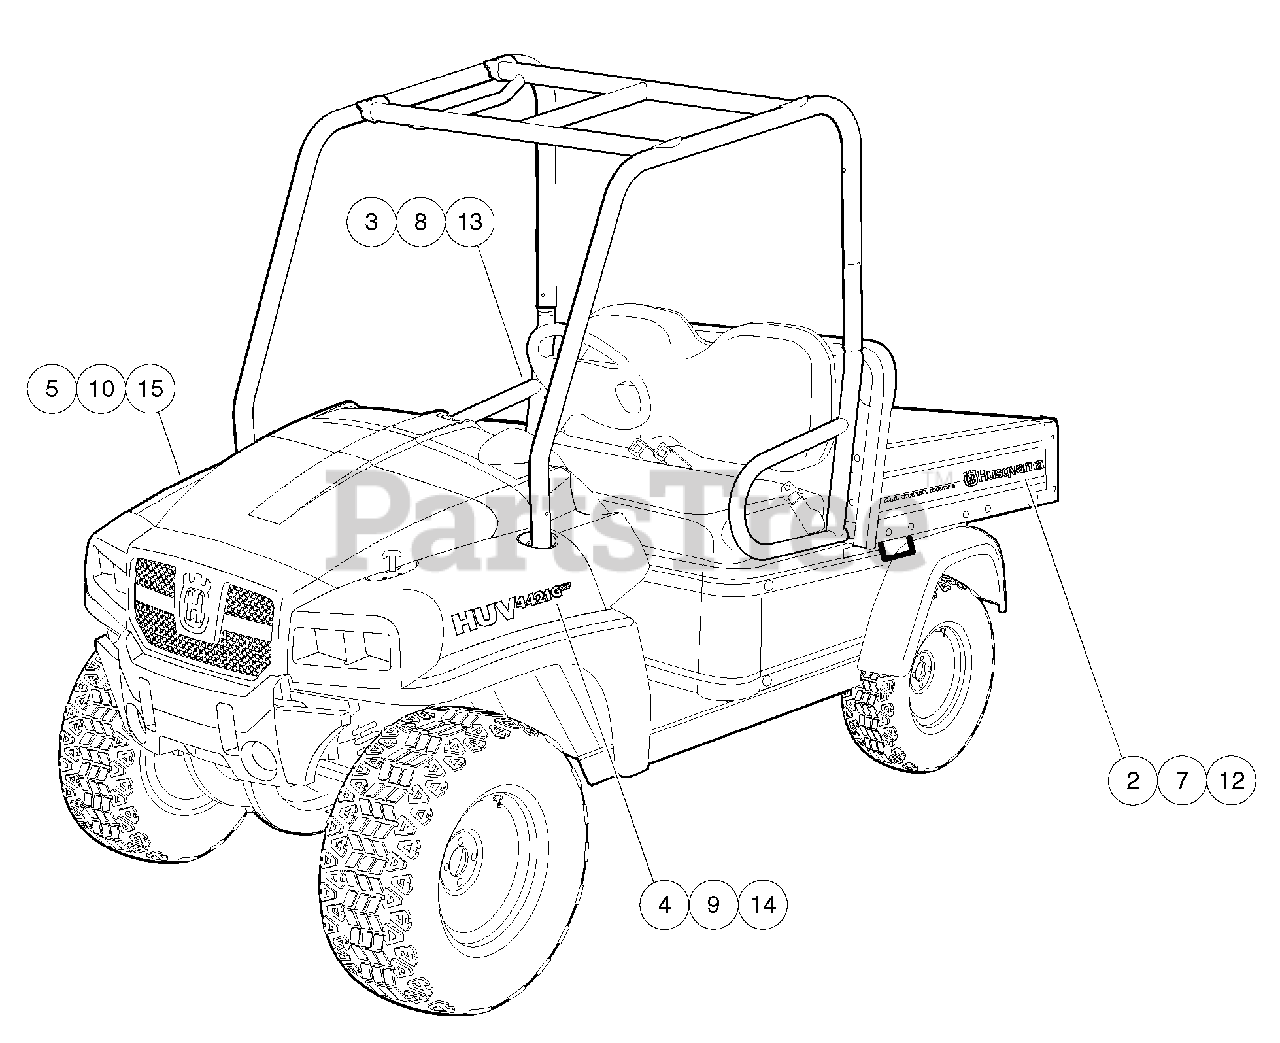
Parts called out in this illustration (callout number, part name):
1	Instl,decal,huv4421gxp,moff
2	Decal, Bed, Huv, Moff, Ds
3	Decal, Bed, Huv, Moff, Ps
4	Decal, Huv 4421gxp, Moff, Ds
5	Decal, Huv 4421gxp, Moff, Ps
6	Instl,decal,huv4421gxp,orange
7	Decal, Bed, Huv, Orange, Ds
8	Decal, Bed, Huv, Orange, Ps
9	Decal,huv 4421gxp, Orange, Ds
10	Decal,huv 4421gxp, Orange, Ps
11	Instl,decal,huv4421gxp,olv Grn
12	Decal, Bed, Huv, Olv Grn, Ds
13	Decal, Bed, Huv, Olv Grn, Ps
14	Decal,huv 4421gxp, Olv Grn, Ds
15	Decal,huv 4421gxp, Olv Grn, Ps
